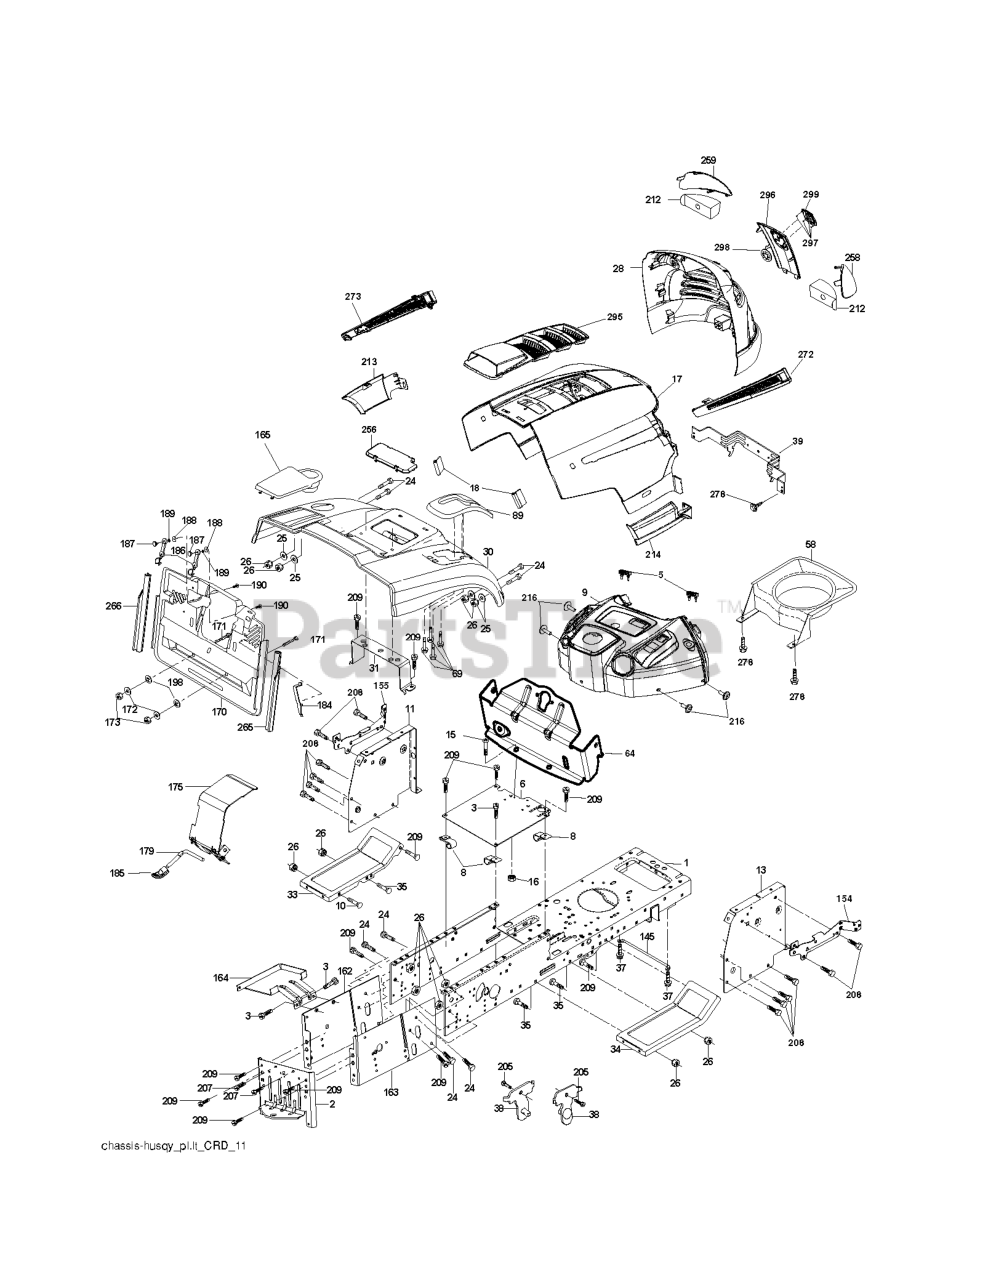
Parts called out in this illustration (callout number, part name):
2	DRAWBAR
3	SCREW 3/8-16X3/4
5	BUMPER.HOOD.TEX.HUSQVARNA
6	PLATE
8	CLIP,INSULATOR
10	BOLT D
11	PANEL.DASH.LH.LTX
13	PANEL ASM, DASH RH
15	Screw, Machine, Truss Head 5/16-18 UNC x 3/4
16	NUT
17	HOOD
18	BUMPER.HOOD.LARGE.1.75"
25	WASHER
26	NUT
28	RP GRILLE/LENS ASM.
30	CONSOLE.CRD.AUTO.GRY
31	BRACKET SUPPORT FENDER
33	FOOTREST PNT LH
34	FOOTREST PNT RH
37	Screw 5/16-18 x 1/2 Hex, Self Tapping 5/16-18 x 1/2
38	BRACKET ASM PIVOT MOWER REAR
39	BRACKET PIVOT
69	SCREW.HI-LO.CONSOLE
145	ROD PIVOT CHASSIS/HOOD
162	BRACKET
163	BRACKET EXTEN CHASSIS RH CRD
165	RP.COVER.BATTERY.CRD.GREY
172	WASHER
175	DOOR TRAP
179	ROD PIVOT FBI
184	BRACKET.ACTUATOR.BAGGER.SRD
186	LATCH ASSY
187	WELDNUT
189	LOCKWASHER #10
190	SCREW
207	SCREW, 5/16-18 X 1/2
208	SCREW 3/8-16X1/2
209	SCREW, 3/8-16X3/4
212	INSERT REFLECTIVE
213	SKIRT SIDE LH
214	SKIRT SIDE RH
216	SCREW HEXWSHR 1/4-20X3/4
256	COVER FENDER CRD
258	LENS.HUSQVARNA LT.RH
259	LENS.HUSQVARNA LT.LH
265	SEALING
266	SEALING
272	VENT SIDE HOOD RH
273	VENT SIDE HOOD LH
278	SCREW
295	VENT TOP HOOD
296	TRIM
297	CLIP.RETAINER.TINNER.
298	NUT PUSH M
299	RP LOGO
